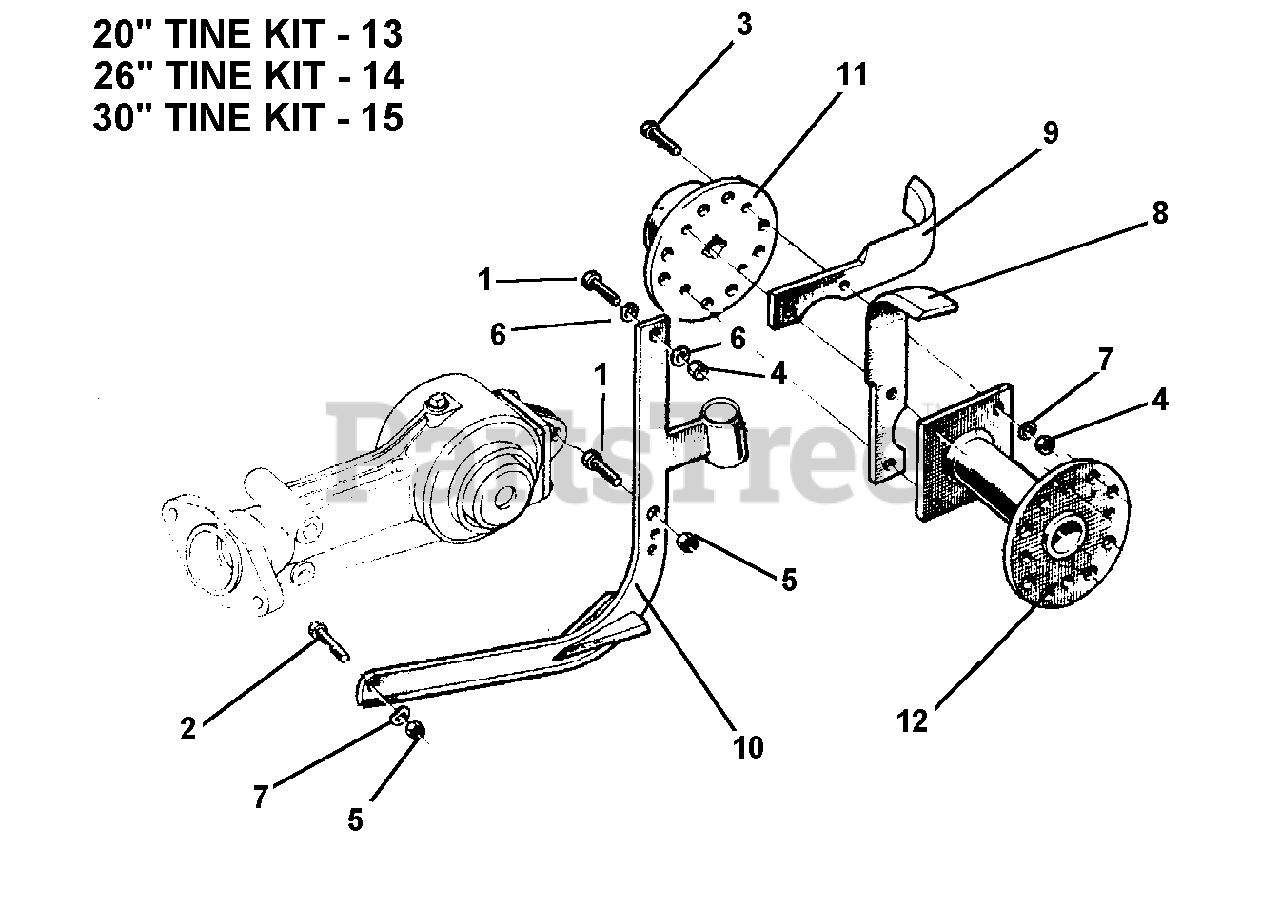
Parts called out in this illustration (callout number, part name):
1	SCREW M8 X 25
2	SCREW M8 X 30
3	SCREW M8 X 35
5	NUT, SELF LOCKING M8
6	WASHER, FLAT 8.4
7	WASHER, LOCK 8.4
9	TINE, RIGHT
10	CENTRAL KNIFE
12	TINE SPACER
13	TINE KIT 20"
14	TINE KIT 26"
15	TINE KIT 30"
